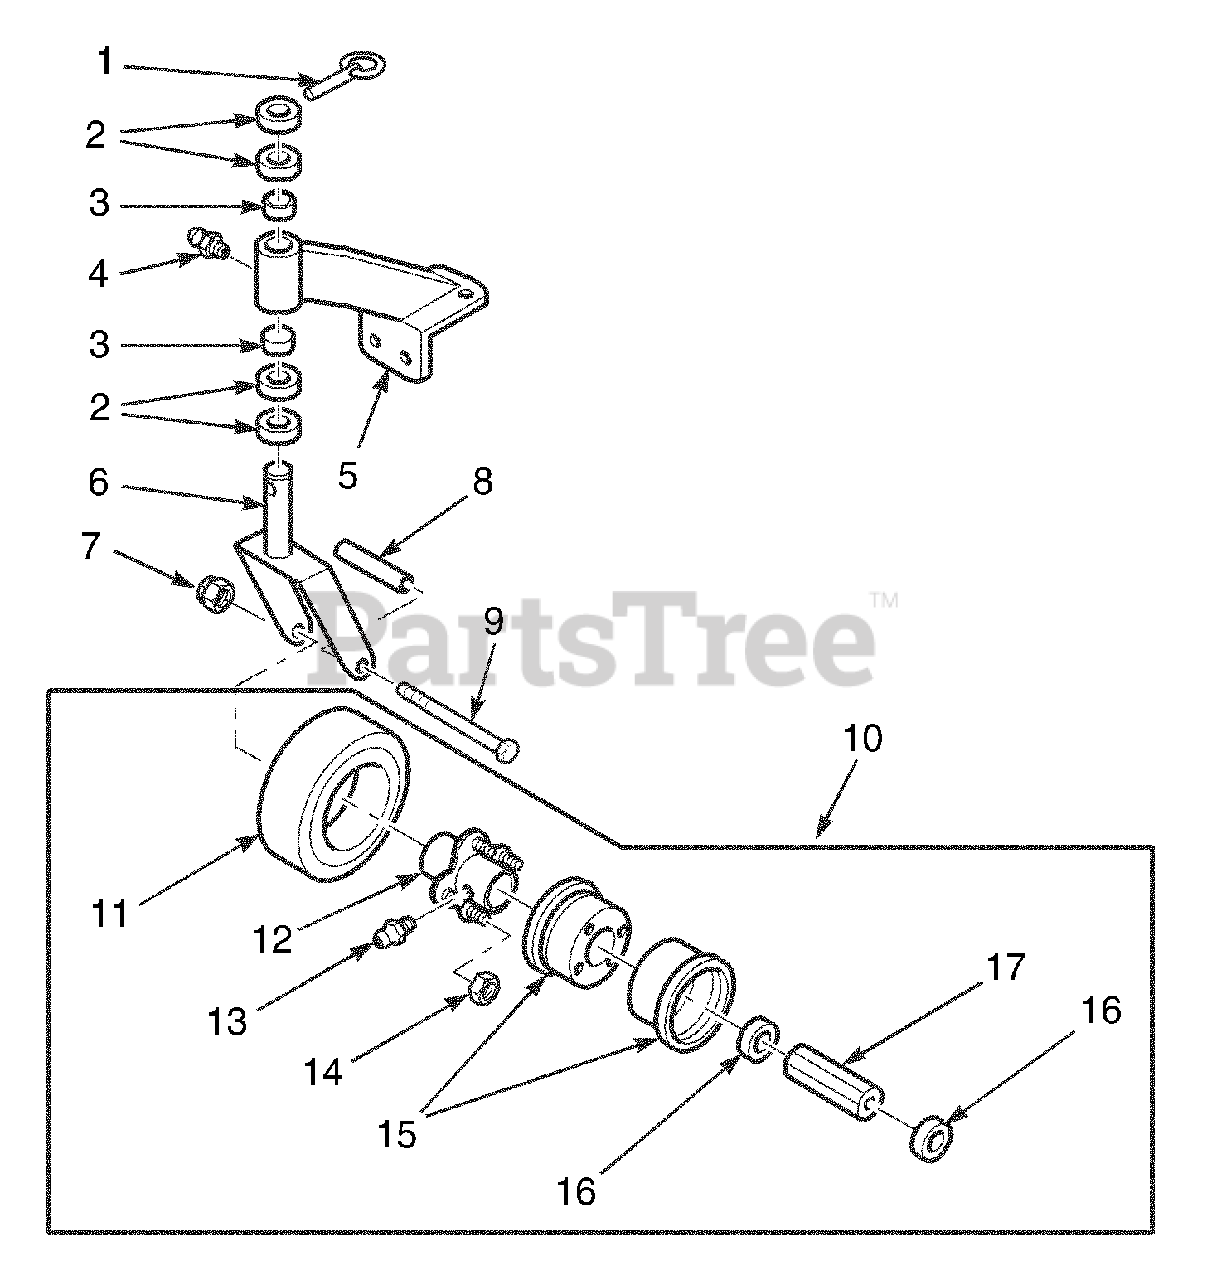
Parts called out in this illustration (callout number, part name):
1	Quick Pin
2	Spacer, Caster Yoke, 1/2" Long
3	Bronze Bearing
4	Grease Fitting
5	Support Assembly
6	Caster Yoke
7	Elastic Stop Nut, 1/2-13
8	Sleeve, Caster Wheel Bearing
9	Hex Hd. Bolt, 1/3-13 x 5-1/2"
10	Wheel Assy.
11	Tire Only, Caster Wheel
12	Hub Assembly
13	Grease Fitting, 45 Degree 1/4-28
14	Tapered Nut, 5/16-24
15	Rim Pair, Caster Wheel
16	Retainer, Bearing, Caster Wheel
17	Roller Bearing, Caster Wheel
